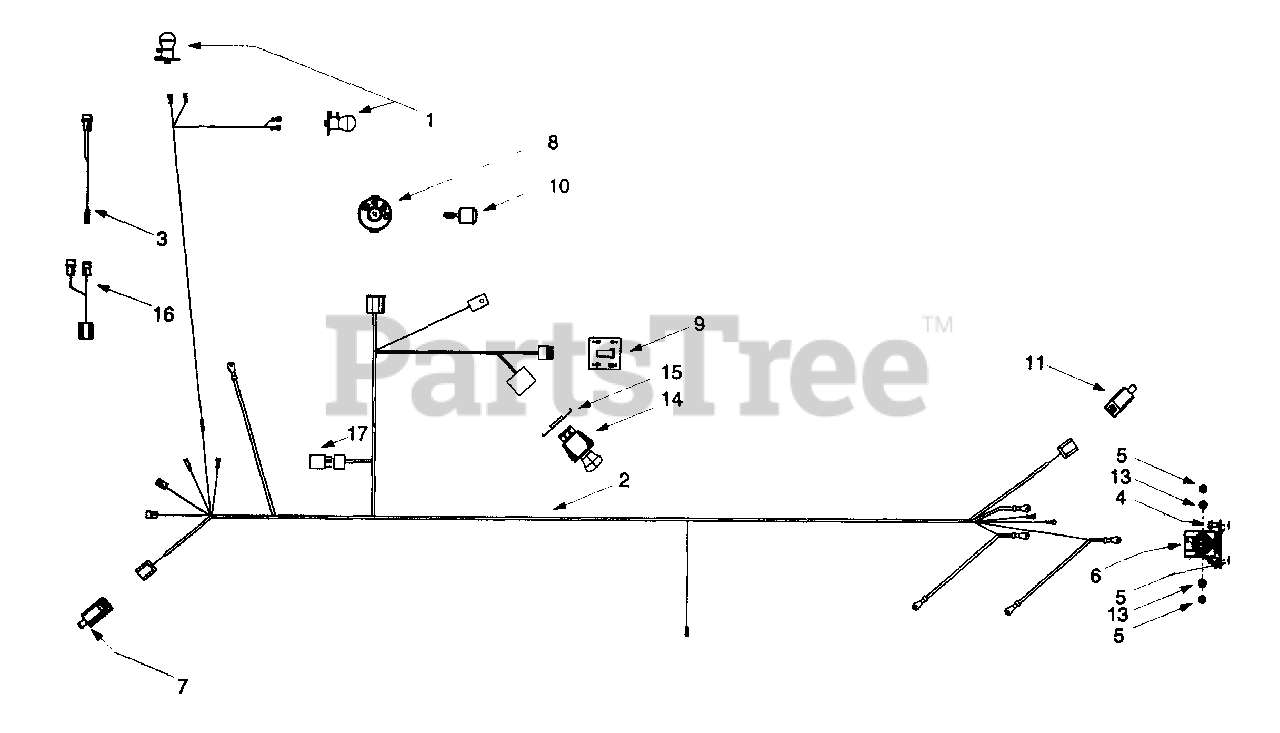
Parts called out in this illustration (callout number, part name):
1	Bulb/Socket Headlight Assembly
2	Wiring Harness
3	Alternator Adapter
4	Self Tapping Screw, 1/4-20 x .5
5	Hex Nut, 1/4-20
6	Solenoid, 12-volt, 100 Amp
7	Snap Mount Safety Interlock Switch
8	Ignition Switch
9	Indicator Monitor / Hour Meter
10	Ignition Key (w/ plastic cover, shown)
11	Safety Plunger Switch
13	Lock Washer, 1/4
14	Electric PTO Switch
15	Retainer Bracket
16	Alternator Adapter
17	Electric PTO Relay
